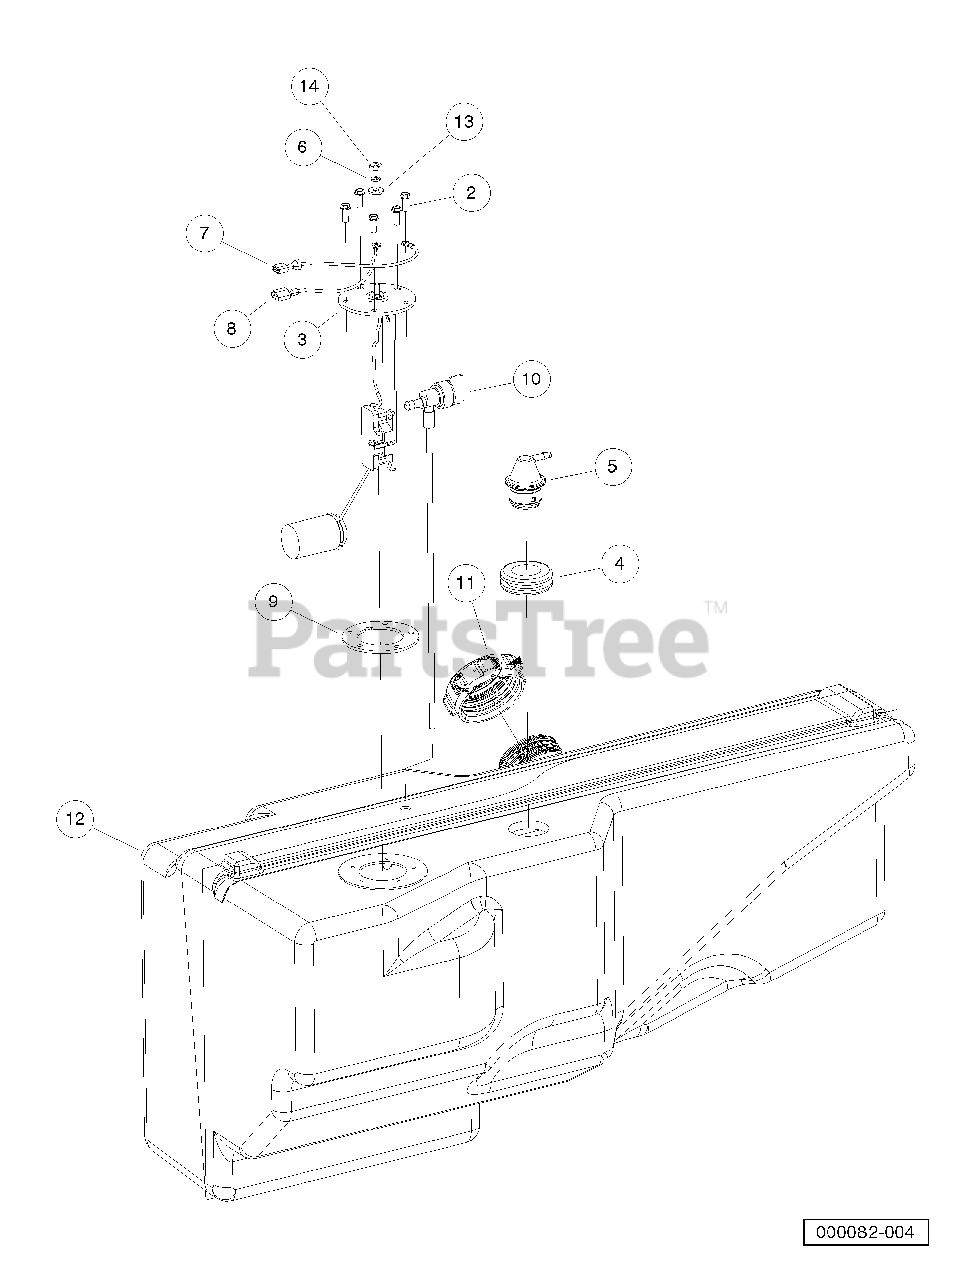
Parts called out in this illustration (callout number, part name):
1	Asm, Tank, Fuel, Gas, 4x4
2	Screw, #10-16 Hex-Head Hi-Lo
3	Sending Unit, Fuel Level
4	Insulation Grommet
5	Vent, Fuel Tank
6	Washer, #10 Split Lock
9	Gasket, Rubber
10	Valve, Pickup Tube, Fuel
11	Cap, Fuel Tank, Gasoline
13	Washer, #10 Type A Flat
14	Nut, #10-32 Brass Hex
